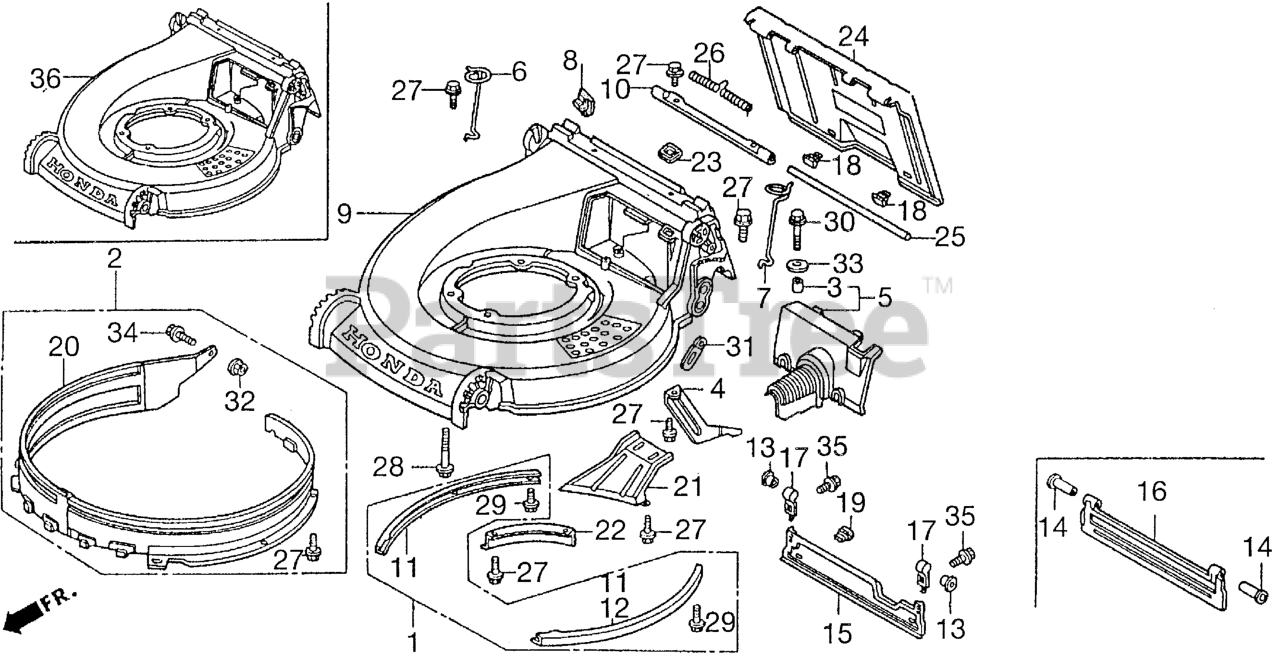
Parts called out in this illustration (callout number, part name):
1	GUARD KIT, HOUSING
2	LINER KIT (INNER) (NOT AVAILABLE)
3	COLLAR, FAN
4	GUIDE, TRANSMISSION MOUNT
5	COVER, DRIVESHAFT *NH192M* (GENTLY SILVER METALLIC)
6	GUIDE, CABLE
7	GUIDE B, CABLE
8	GROMMET D, CABLE
9	HOUSING, CUTTER *NH190M* (VINTAGE GRAY METALLIC)
10	HINGE, DISCHARGE GUARD
11	GUARD KIT, HOUSING
13	BUSH, SAFETY SHIELD
15	SHIELD, SAFETY
17	HANGER, SAFETY SHIELD
18	STOPPER, DISCHARGE GUARD
19	STOPPER, DISCHARGE GUARD Use up to Frame SN 1186736.
20	LINER (INNER)
21	GUIDE, SCROLL
23	GROMMET C, CABLE
24	GUARD, DISCHARGE
25	SHAFT, DISCHARGE GUARD
25	SHAFT, HINGE (NOT AVAILABLE)
26	SPRING, GUARD RETURN
27	BOLT, FLANGE (6X12) (CT200)
28	BOLT, ENGINE SETTING
29	BOLT, FLANGE (6X12) (CT200)
30	BOLT, FLANGE (6X25)
32	NUT, FLANGE (6MM)
33	WASHER, PLAIN (6MM)
34	BOLT, FLANGE (6X16)
35	BOLT, FLANGE (6X12) Use up to Engine SN 1543277.
36	HOUSING, CUTTER *NH190M* (VINTAGE GRAY METALLIC)
